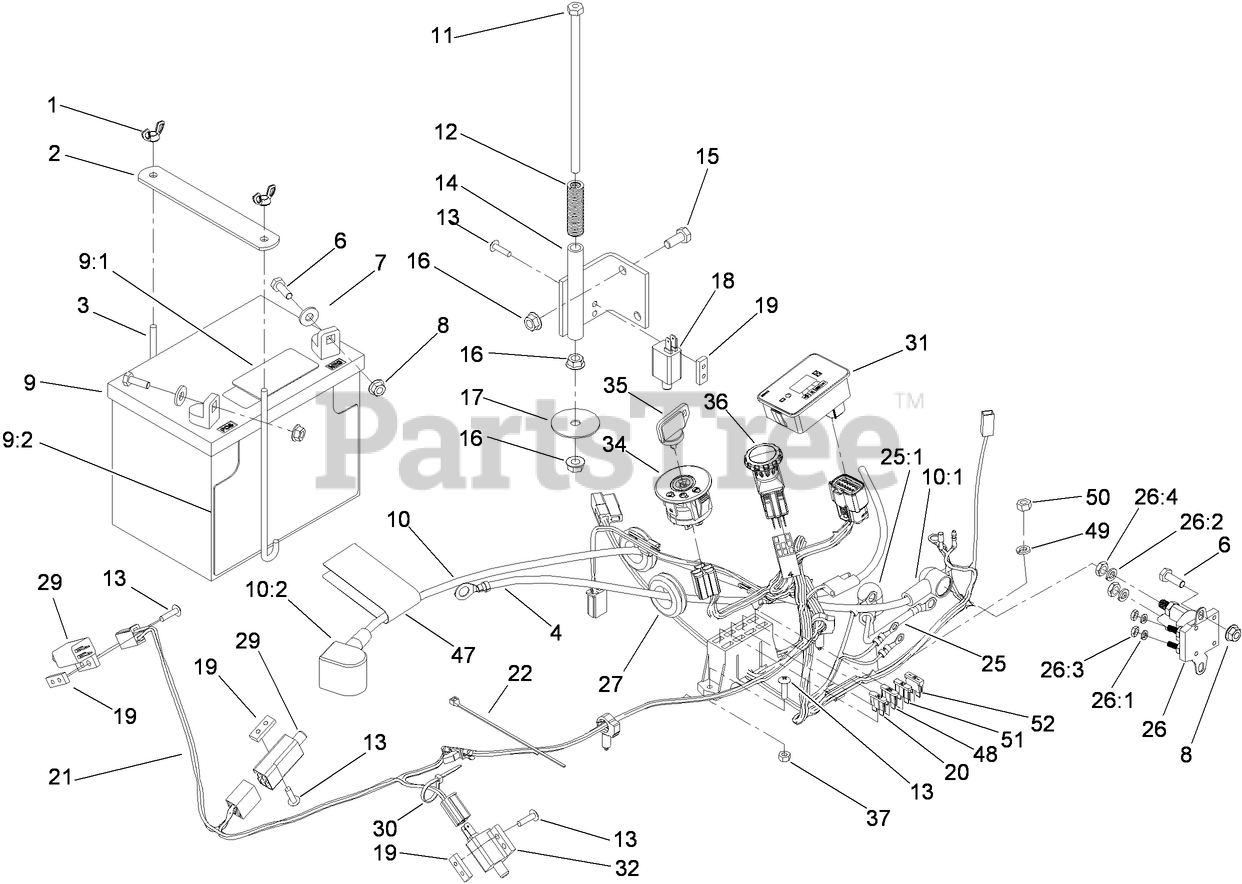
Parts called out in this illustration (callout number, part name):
1	WINGNUT
2	STRAP-HOLDDOWN, BATTERY
3	BOLT-HOLDDOWN
4	CABLE-GROUND, NEGATIVE
6	SCREW-HH
7	WASHER-FLAT
8	NUT-HF
9	BATTERY
9:1	Decal-Battery
9:2	Decal-Battery
10	POSITIVE BATTERY CABLE ASM
10:1	INSULATOR-SOLENOID
10:2	INSULATOR-BATTERY
11	SCREW-HH
12	SPRING-SWITCH, SEAT
13	SCREW-HEAD, TRUSS
14	BRACKET-SWITCH, SEAT
15	SCREW-HH
16	NUT-HF
17	WASHER
18	SWITCH-CLOSED, NORMALLY
19	PLATE-TAPPED
20	FUSE-BLADE, 30 AMP
21	HARNESS-ELECTRICAL
22	TIE-CABLE
25	POSITIVE STARTER CABLE ASM
25:1	INSULATOR-SOLENOID
26	SWITCH-SOLENOID
26:1	WASHER-LOCK
26:2	WASHER-LOCK
26:3	NUT-HEX
26:4	NUT-JAM
27	GROMMET
29	SWITCH-OPEN, NORMALLY
30	TIE-PLASTIC
31	HOUR METER ASM
32	SWITCH
34	SWITCH-IGNITION
35	KEY-IGNITION
36	SWITCH-PTO, 10 AMP
37	NUT-LOCK, NI
47	DECAL-INSTRUCTIONS, CHARGING
48	FUSE-BLADE, 25 AMP
49	WASHER-LOCK
50	NUT-HEX
51	FUSE-BLADE, 10 AMP
52	FUSE-BLADE, 15 AMP
